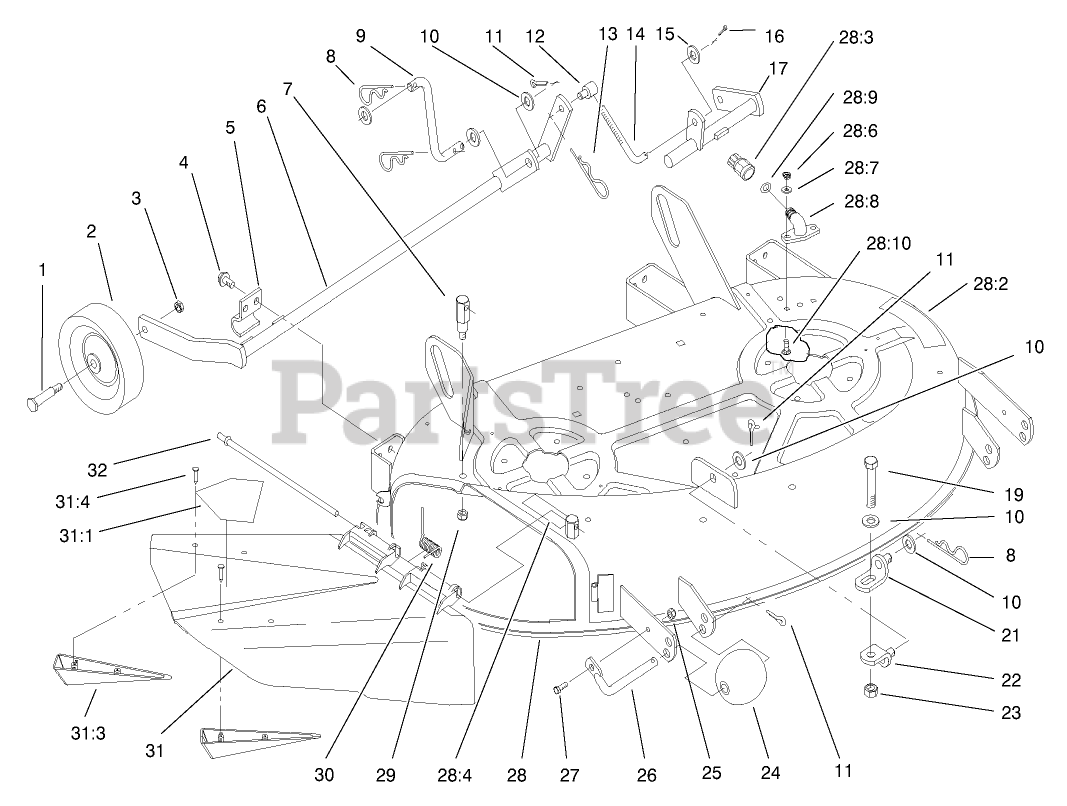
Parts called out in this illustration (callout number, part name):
1	BOLT-SHOULDER
2	WHEEL
4	SCREW-HWH, TAPTITE
6	SHAFT ASM-RH
7	PIVOT POST - REAR
8	PIN-COTTER, HAIR
9	LINK-REAR
10	WASHER-FLAT
11	PIN-COTTER
12	TRUNNION
13	PIN-HAIR
14	ROD-LIFT
15	WASHER-FLAT
16	PIN-COTTER
19	SCREW-HH
21	BRACKET-LIFT, LOWER
22	BRACKET-LIFT, UPPER
23	NUT-JAM
24	ROLLER
25	NUT-LOCK, NI
26	SHAFT-ROLLER
27	SCREW-HH
28:2	DECAL-DANGER
28:3	CONNECTOR-HOSE
28:4	DECAL-CAUTION
28:6	NUT-LOCK, NI
28:7	WASHER-FLAT
28:9	O-RING
28:10	BOLT-CARR
29	NUT-LOCK, NI
30	SPRING
31:1	DECAL-DANGER
31:3	KICKER
31:4	SCREW-PPH
32	ROD-HINGE DEFLECTOR
